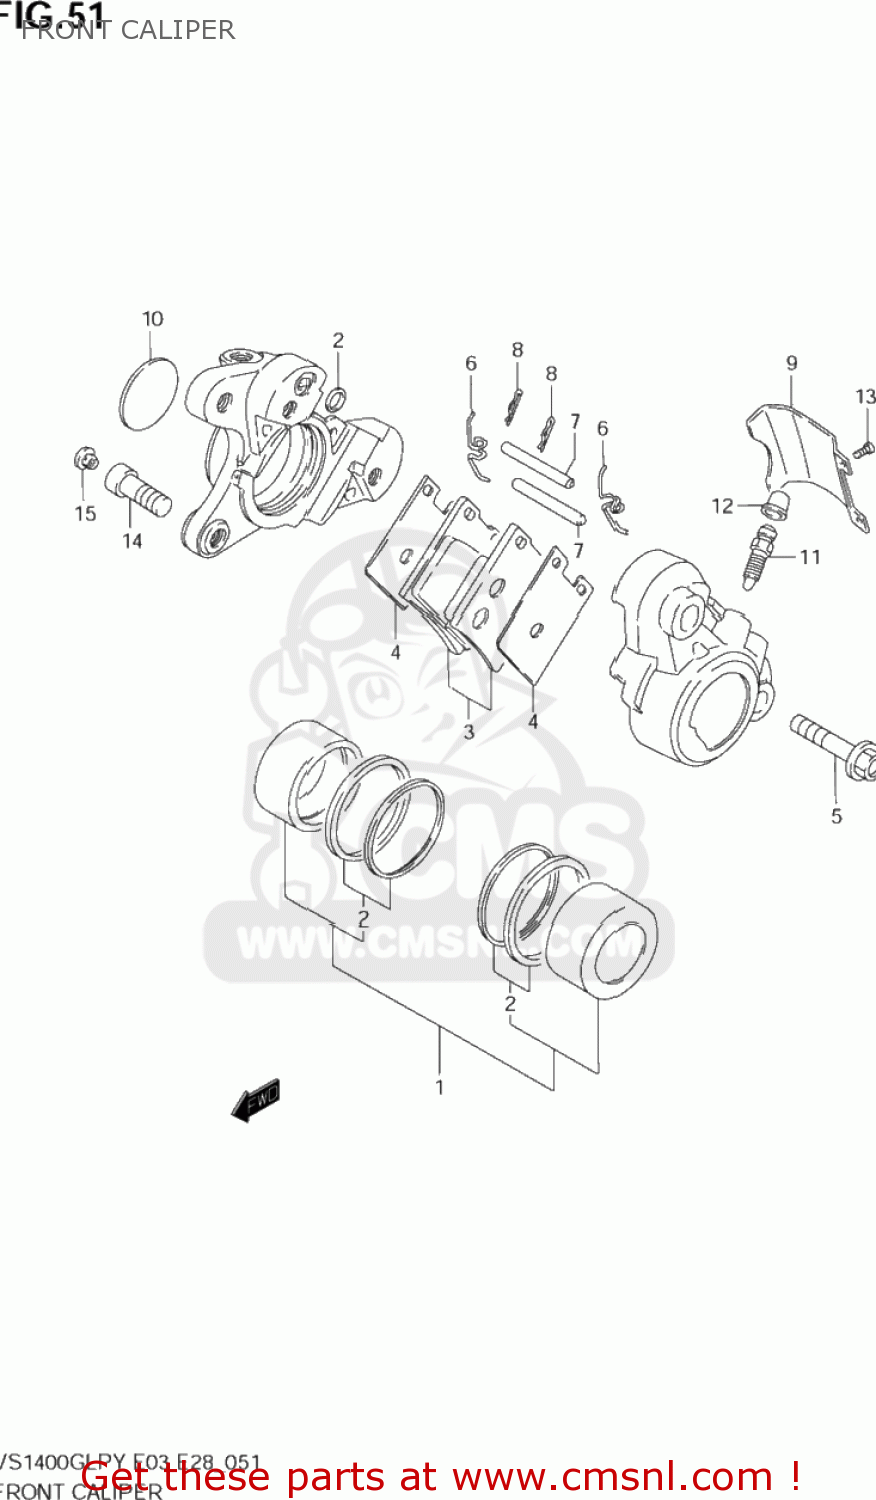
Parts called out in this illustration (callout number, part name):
1	PISTON SET
2	SEAL SET,PISTON
3	PAD SET (NAS)
4	SHIM,PAD
5	BOLT,HOUSING
6	SPRING
7	PIN,PAD
8	CLIP,PAD PIN
9	COVER,CALIPER HOUSING,DUST
10	CAP,CALIPER
11	BLEEDER
12	CAP,BLEEDER PLUG
13	SCREW,CALIPER COVER(4X6)
14	BOLT(10X33)
15	CAP(OD:12)
